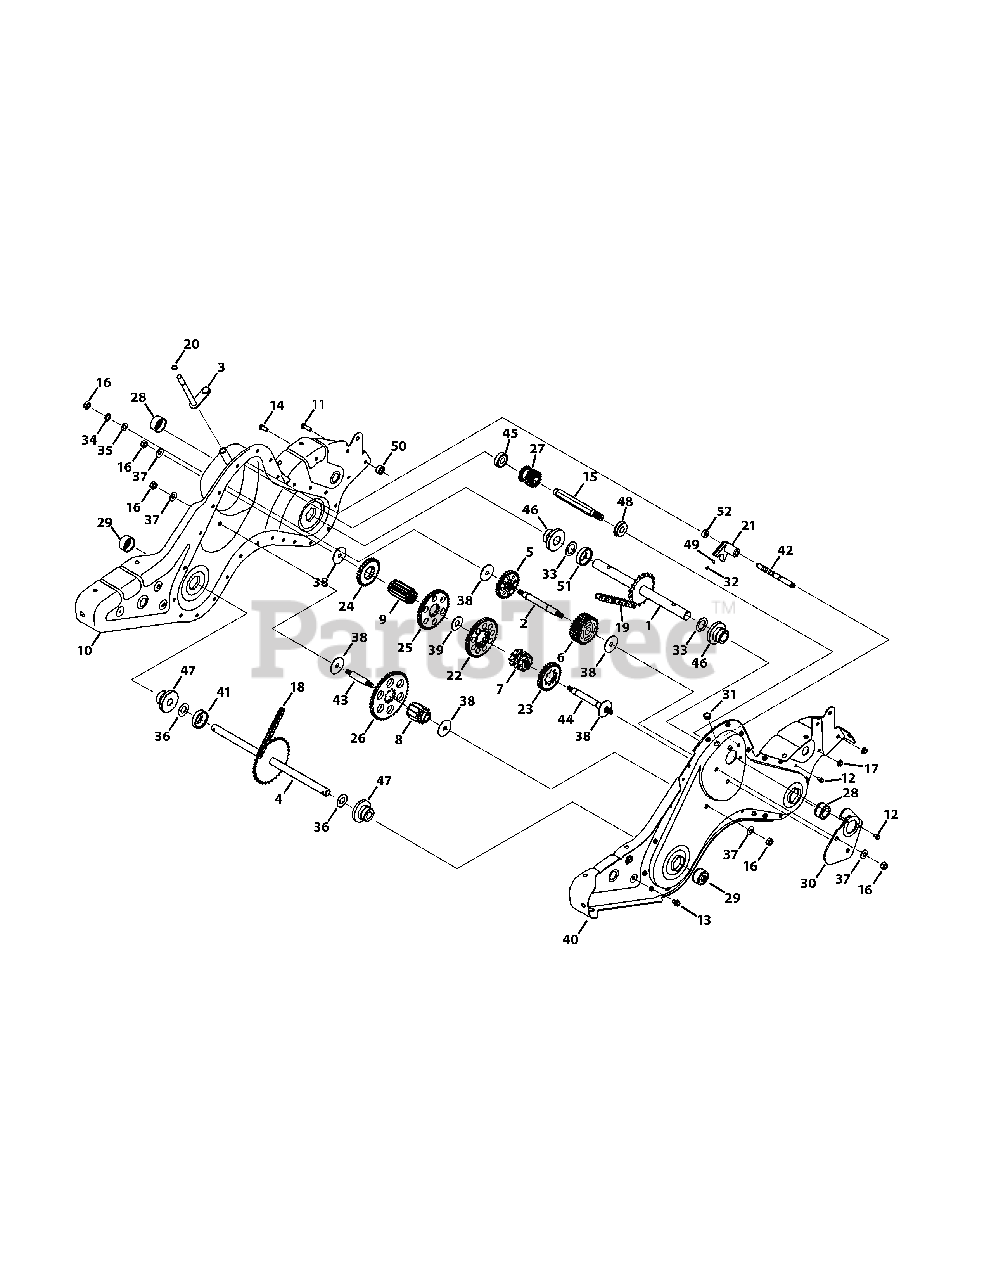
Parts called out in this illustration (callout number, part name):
1	Shaft Assembly, Tine, 18T
2	Shaft Assembly, Jack
3	Shaft Assembly, Shift Input
4	Shaft Assembly, Wheel, 33T
5	Gear Assembly, 30T Reverse Idler
6	Gear Assembly, 30T Tine Idler
7	Sprocket Assembly, 9T Tine Input
8	Sprocket Assembly, 10T Whl Input
9	Gear Assembly, 11T
10	RH Chain Case Housing Assembly
11	Hex Head Screw, 5/16-18 x 1.00
12	Screw, 1/4-20 x 0.500
13	Screw, :5/16-18 x 0.625
14	Hex Head Screw, 5/16-18 x .75
15	Input Shaft, .75
16	Nut, Hex, 7/16-20
17	Nut, Flangelock, 5/16-18
18	Endless Chain, #420 x 50 Links
19	Endless Chain, #50 x 54 Links
20	Snap Ring, .500
21	Clutch Collar
22	Gear Spur, 44T
23	Gear Spur, 30T
24	Gear Spur, 30T
25	Gear Spur, 44T
26	Gear Spur, 44T
27	Gear Spur, 16T
28	Shaft Seal, 1.0
29	Shaft Seal, .75
30	Positioner Gear Bracket
31	Tapered Cap Plug
32	Compression Spring, .230 OD
33	Washer, Flat, 1.03 x 1.62 x .03
34	Washer, Lock, 7/16
35	Washer, Flat,.474 x .879 x .064
36	Washer, Flat, .760 ID x 1.50 OD
37	Washer, Bell,.45 x 1.00 x .062
38	Washer, Thrust, .445 x 1.92 x .060
39	Washer, Flat,1.595 x .635 x .062
40	LH Chain Case Housing
41	Spacer, .75 x 2.0 x .50
42	Shaft Detent, .5 DIA
43	Shaft, Jack, .625 x 2.385
44	Shaft, Jack, .6250 x 5.0050
45	Ball Bearing, 17 x 40 x 12:6203
46	Flange Bearing, 1.0 x 2.5 x 1.38
47	Flange Bearing, .75 x 2.5 x 1.38
48	Ball Bearing, 17 x 40 x 12:6203
49	Ball, Detent, .250
50	Spacer, .315 x .750 x .375 LG
51	Spacer, 1.0 ID x 2.0 OD x.5 LG
52	Spacer, .505 ID x .88 OD x .440
